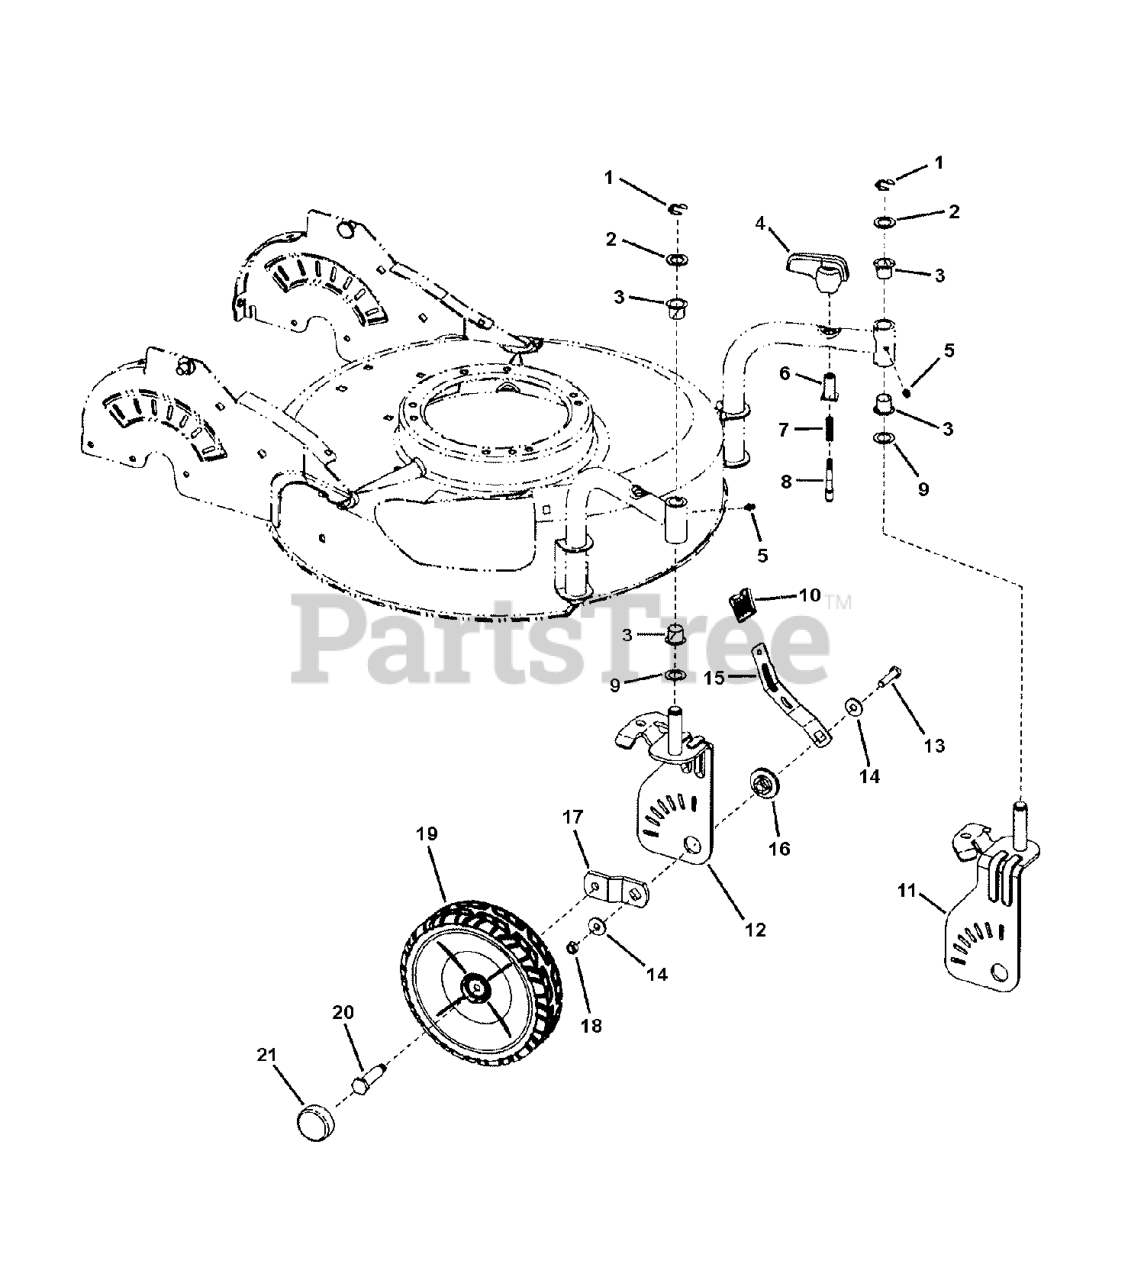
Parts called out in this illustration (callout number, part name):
1	RING, Klipring Ext.
2	WASHER, .64 x .99 x .025, Flat
3	NYLINER, 5/8
4	KNOB, Quick Release
5	LUBE FITTING, 3/16
6	BUSHING, Handle Pin
7	SPRING, Compression
8	PIN, Handle Adjust
9	WASHER, .64 x .99 x .05, Flat
10	GRIP, Height Latch
11	WELDMENT, Swivel Wheel Brkt, LH
12	WELDMENT, Swivel Wheel Brkt, RH
13	SCREW, 5/16-18 X 1.25 Hex Head Cap, GR 5
14	WASHER, .875 x .327 x .090, Flat
15	LEVER, Height Adjust, Swivel Wheel
16	SPACER, Swivel Wheel Pivot
17	AXLE PLATE, Swivel Wheel
18	NUT, 5/16-18 Hex Center Lock
19	ASSY, WHEEL, 8 x 2 Idle, JD Tread, BB, Yellow
20	AXLE, Swivel Wheel, 1-5/8
21	HUBCAP, Round, JD Yellow
